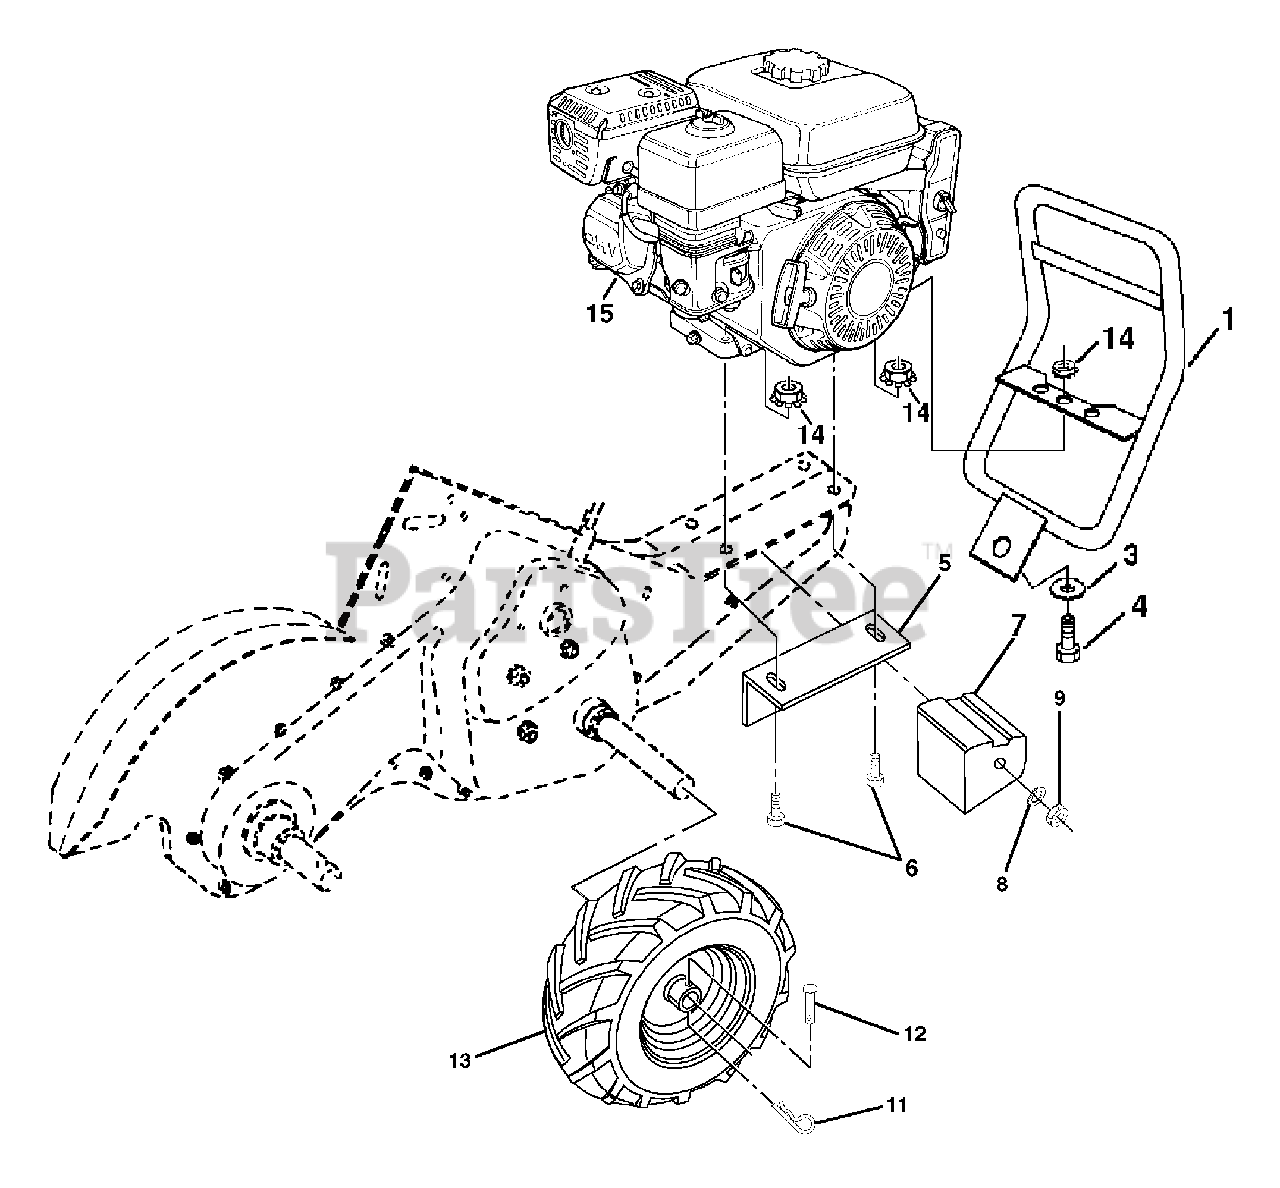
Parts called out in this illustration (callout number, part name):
2	Nut Lock Hex Flange
3	Washer 11/32 x 11/16 x 16 Ga.
4	Bolt Hex Hd 5/16-18 x 3/4
5	Bracket, Reinforcement
6	Bolt, Hex 5/16-18 x 1-1/2
7	Counter Weight, R.H.
8	Washer, Lock 3/8
9	Nut, Hex 3/8-16
11	Clip, Hairpin
12	Rivet, Drilled
13	Rim
13	Tire Valve
14	Nut, Keps 5/16-18
15	Engine
